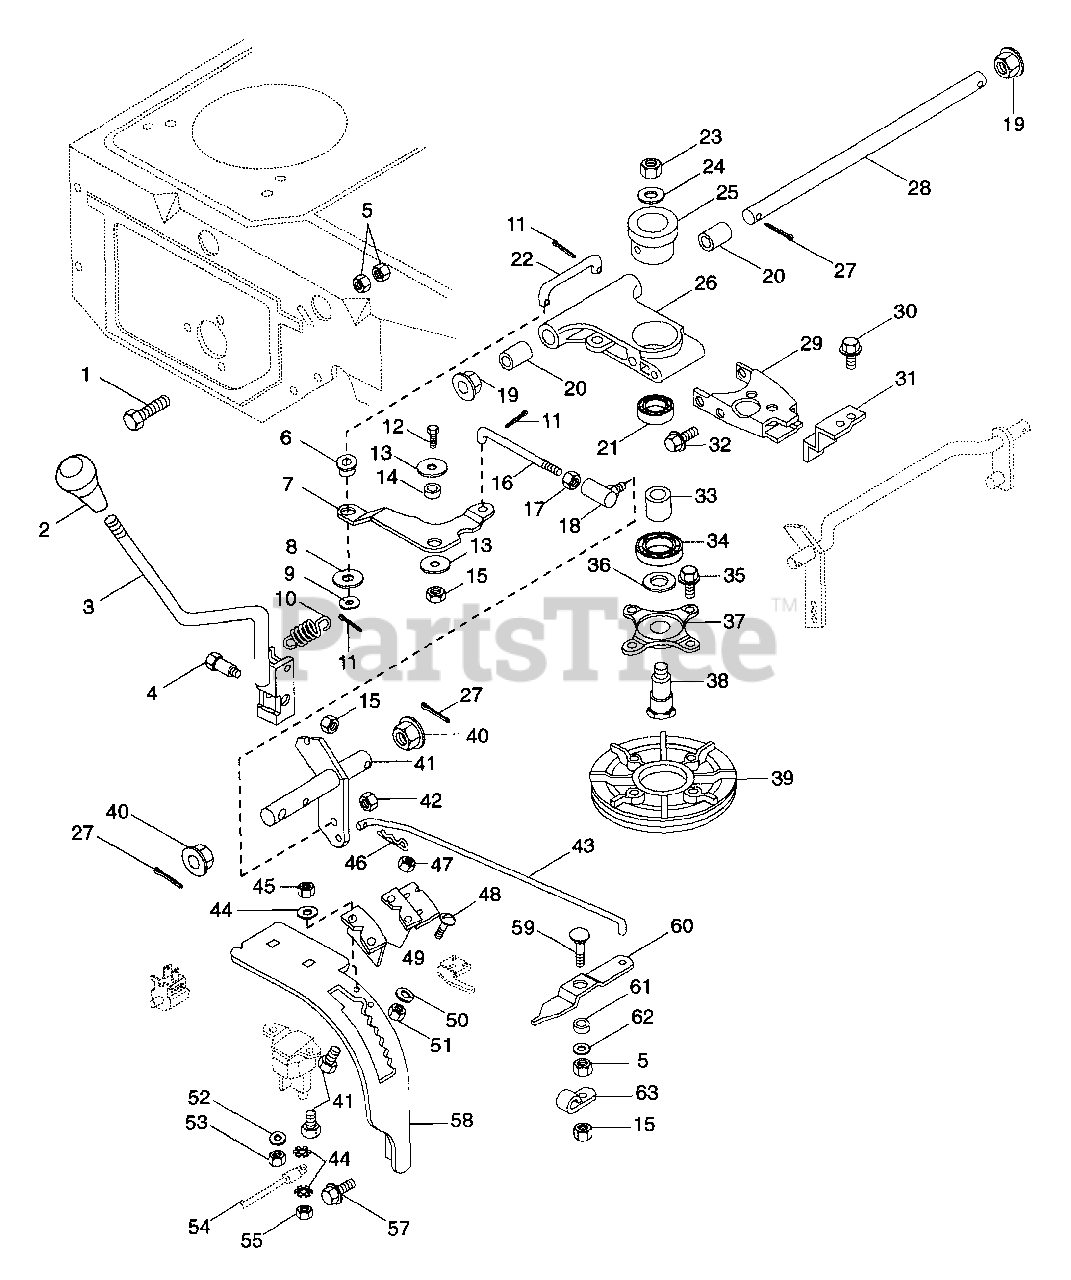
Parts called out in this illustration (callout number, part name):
1	BLT-HEX .31-18X1.50 GR2 YWZC
3	SHIFT LEVER
4	SHOULDER BOLT .436 X .912
5	NUT-HEX .312-18
5	BSHG-FLG .372X.500X.312X.625NY
7	BELL CRANK
8	WSHR-FL-STL .531X1.250X.100 PL
9	WSHR-FL-STL .380X.626X.033
10	SG-TENS .092X.69X1.75 WLD 54
11	PIN-COTR .09X.75 PL
12	BLT-HEX .31-18X.75 PL GR2
13	WSHR-FL-STL .344X1.125X.063PL
14	SPACER BUSHING .5 X .32 X .21
15	NUT-LK .312-18 GR A PL
16	SHIFT ROD
17	NUT-HEX .312-24 PL
18	BALL JOINT- SNAP IN
19	FLANGE BUSHING
20	BSHG-SLV .625X.750X.500 BR
21	BRG-BALL .625X1.375X.44
22	SHIFT LINK
23	NUT-LK-CTR .50-20 PL
24	WSHR-HDND-STL-THR.515X.97X.062
25	BEARING HOUSING
26	CARRIER ASSEMBLY
27	PIN-COTR .12X1.0 PL
28	TRANSFER SHAFT
29	CARRIER YOKE
30	SCR-TAP .312-18X.50 HWH PL TR
31	NEUTRAL STOP
32	SCR-TAP .312-18X.75 HWH PL TR
33	BSHG-SLV .634X1.000X.465
34	BRG-BALL .750X1.781X.61
35	SCR-TAP.250-20X.62 HWH BLK ZC
36	WSHR-HDND-THRST .758X1.23X.031
37	DISC ADAPTER
38	SPINDLE BOLT
39	DRIVE CARRIER ASSEMBLY
40	FLANGE BUSHING
41	SHIFT ARM
42	NUT-LK-CTR .312-24 PL
43	INDICATOR ROD
44	WSHR-LK-EXT. 250 ID
45	NUT-HEX .250-20 PL
46	PIN-COTR .06X.50
47	NUT-LK-CTR .250-20 PL
48	SCR-MCH 10-24X1.00 SLRH PL
49	BRACKET NEUTRAL SWITCH
49	BRACKET- NEUTRAL
50	WSHR-LK 10X.047 MED PL
51	NUT-HEX 10-24 PL
52	WSHR-LK-EXT #10 ID X .022
53	NUT 10-32 PL
54	CABLE TIE LG 5-1/2
55	NUT-JAM .312-24 PL
56	BLT-HEX .25-20X.50 PL GR5
57	SCR-TAP .250-20X.50 HXSLHDPL
58	QUADRANT
59	BLT-RDHDSQNK .31-18X1.0 SHT PL
60	INDICATOR
61	SPACER BUSHING .5 X .32 X .163
62	WSHR-FL-STL .323X.625X.062 PL
